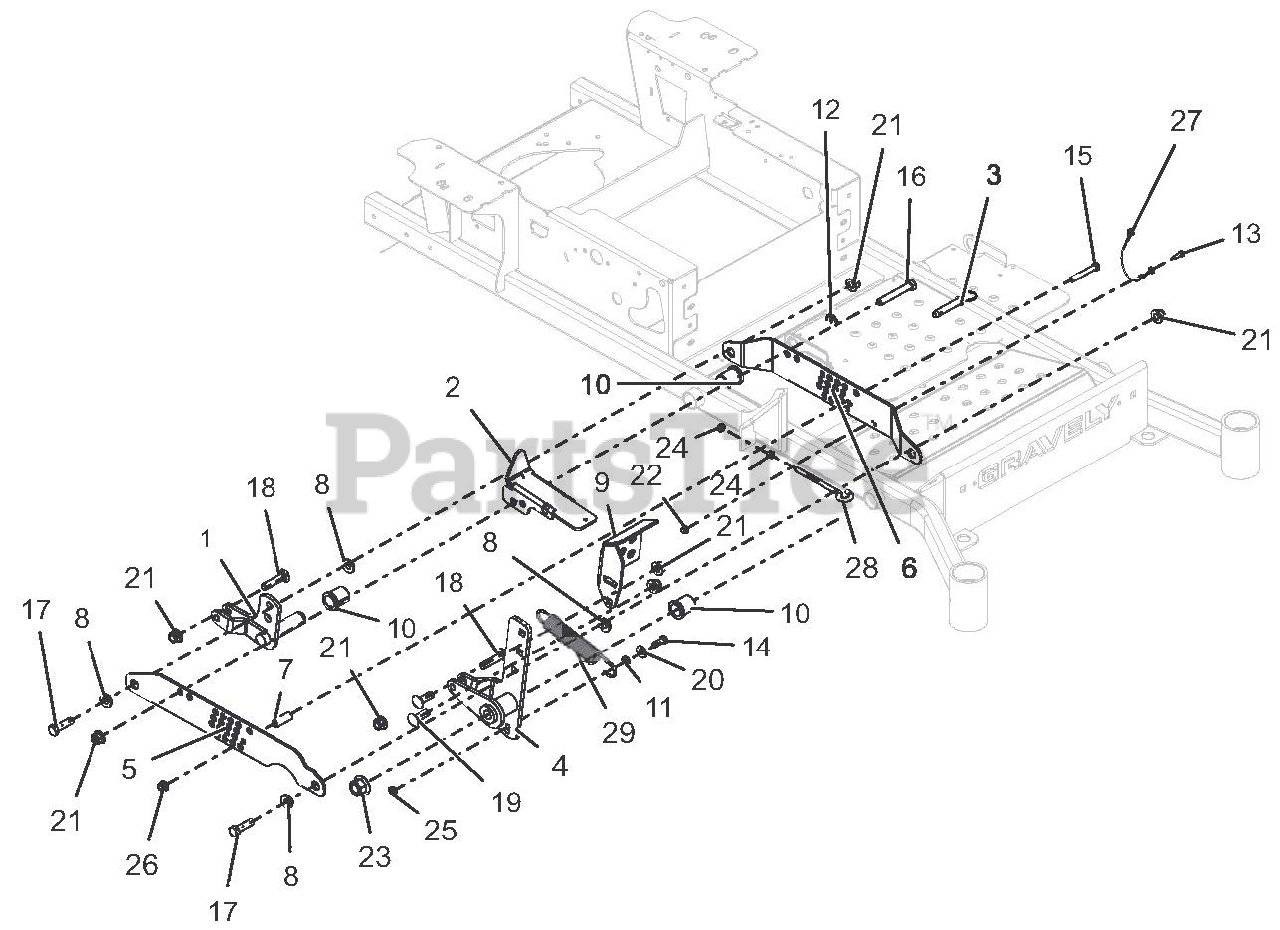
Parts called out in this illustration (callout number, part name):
1	WLDMT, RH REAR DECK LIFT
2	WLDMT, MECHANICAL LOCK-UP-BLACK
3	PIN, .500 x 2.000 USABLE LG BALL
4	WLDMT, TAPERED LIFT ARM FRONT LH-BLACK
5	BRKT, RH OUTBOARD LIFT/CUT HEIGHT-BLACK
6	BRKT, RH INBOARD LIFT/CUT HEIGHT-BLACK
7	SPACER, .375 X .625 X 1.54
8	BSHG, FLANGE .515X.750X.31X1.12
9	PEDAL, ADJUSTABLE FOOT LIFT
10	BSHG-FLG 1.00X1.25X1.5X1.5
11	BSHG, SLV .377X.624X.235
12	RG-RTNG-EXT 1.00X.078
13	BLT-HEX .25-20X.75 GR5 YWZC
14	BLT-HEX .38-16X1.00 GR5 YWZC
15	BLT-HEX .38-16X2.50 GR5 YWZC
16	BLT-HEX .50-13X3.25 GR5 YWZC
17	BLT-HEX .50-13X1.75 GR5 YWZC
18	BLT-RDHDSQNK .50-13X2.25 G5 Y
19	BLT-RDHDSQNK .50-13X1.50 G5 YWZC
20	WSHR-FL-STL.438X1.00X.083 YWZC
21	NUT-LK-NYL-FLG .50-13 YWZC
22	NUT-LK-NYL-FLG .25-20 YWZC
23	NUT-LK-NYL-FLG .75-10 YWZC
24	NUT, JAM .375-16 YWZC
25	@NUT-LK-CTR-JAM .375-16 YWZC
26	NUT-LK-NYL-FLG .38-16 YWZC
27	LANYARD, 12"
28	BOLT, EYE .38-16X6.00 .62 DIA
29	SPRG, TENSION .162 X 1.250 X 8.250
